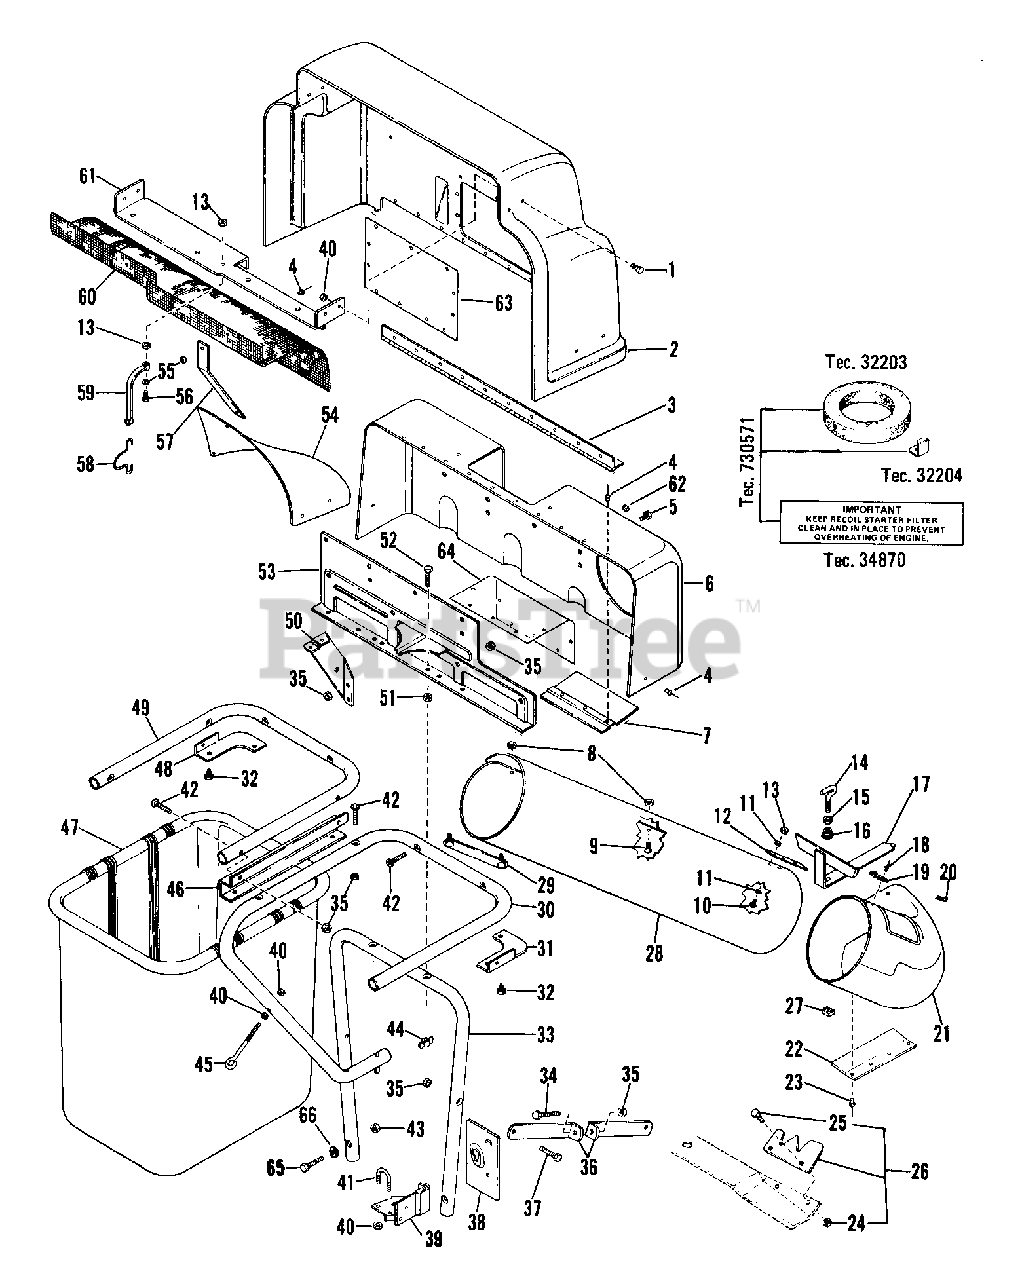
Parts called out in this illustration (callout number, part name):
1	BLT-HEX .25-20X.50 PL GR2
2	HINGED COVER W/DECALS
4	RVT-POP .187X.402 DOME ST
5	SCR-MCH .31-18X.75 TSKBHD PL
6	STATIONARY COVER
7	TUBE GUIDE
8	NUT-LK-FLG .250-20 PL
9	BLT-RDHDSQNK .25-20X.50 SHT PL
10	SCR-MCH 10-24X.50 SLRH PL
11	WSHR-FL-STL .219X.500X.049 PL
13	NUT-LK TOP 10-24 PL
14	CLAMP SCREW
15	NUT-LK-TWIN .312-18 PL
16	NUT-FLG. .312-18 PL
17	BRACKET
18	RVT-TBLR .187X.375 OH ST PL
19	RETAINER
20	PIN-HAIR INT .09X.188 PL
21	BOOT ASSEMBLY 32"
22	EXTENSION CHUTE
23	RVT .187X.343 TR ST PL
24	NUT-LK TOP .312-24 PL GR C
25	BLT-HEX .31-24X.75 GR8
26	SERVICE VANE PACKAGE
27	NUT-RTNR .31-18 TINRMAN
28	TUBE BLANK
30	RIGHT TUBE
31	RH CORNER BRACKET
32	SCR-TAP .312-18X.50 HWH PL TR
33	BAR SUPPORT
34	BLT-HEX .31-18X2.75 PL GR2
35	NUT-LK .312-18 GR A PL
36	BRACKET - ADJUSTMENT
37	BLT-HEX .31-18X1.50 PL GR2
38	BRACKET ADAPTER
39	BRACKET MOUNTING
40	NUT-LK-CTR .250-20 PL
42	SCR-MCH .31-18X1.50 CROVCNTRS
43	NUT-LK-NYL.312-18 PL
44	NUT-WING W/INSERT .312 - 18
45	EYEBOLT
46	TUBE BRACKET
47	GRASS BAGGER BASKET
48	LH CORNER BRACKET
49	CENTER TUBE
51	NUT-HEX .312-18
52	BLT-HEX .31-18X1.50 GR2 YWZC
53	MOUNTING BRACKET
55	WSHR-FL-STL .194X.492X.047 PL
56	SCR-MCH 10-24X.88 SLRH PL
59	BATTERY STRAP
61	COVER BRACKET
62	WSHR-FL-STL .344X1.125X.063PL
63	STATIONARY COVER WINDOW
64	STATIONARY COVER
65	BLT-HEX .31-18X1.50 PL GR2
66	WSHR-FL-STL.344X.688X.065PL
